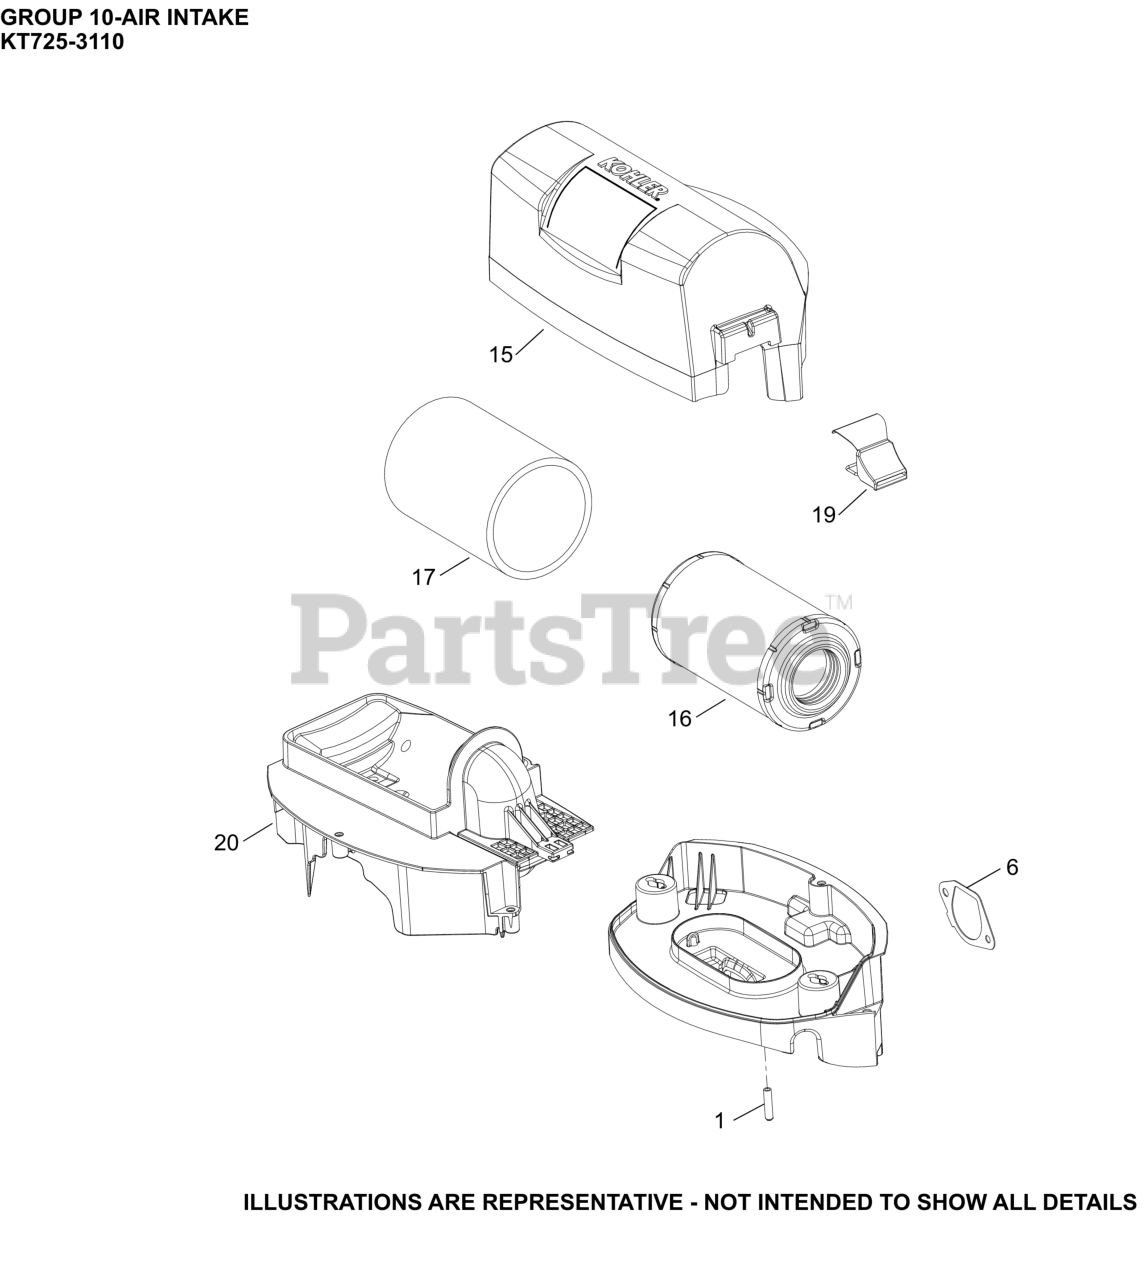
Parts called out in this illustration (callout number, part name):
1	CAP, MASKING
6	GASKET, AIR CLEANER BASE
15	COVER, AIR CLEANER
16	ELEMENT, AIR FILTER
17	ELEMENT, PRE-CLEANER
19	LATCH ASSY, AIR CLEANER COVER
20	BASE, ASM. AIR CLEANER (CYLINDRICAL)
